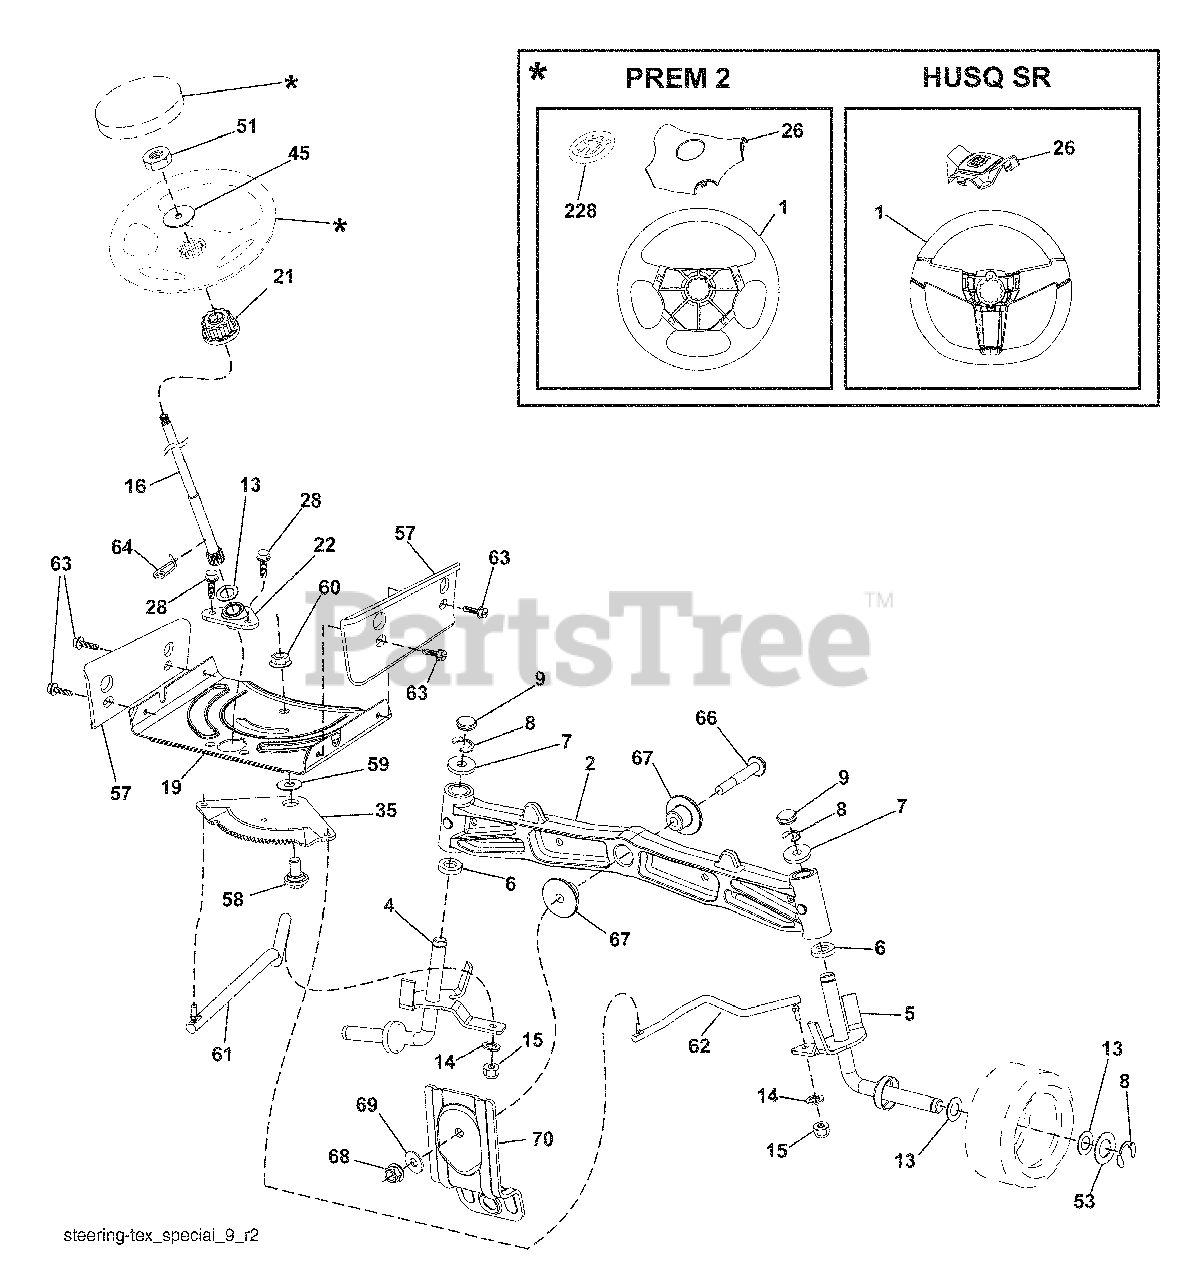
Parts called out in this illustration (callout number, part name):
1	Wheel, Steering
2	Axle Asm., Front
4	Spindle Asm., LH
5	Spindle Asm., RH
6	Bearing, Race Thrust Harden
7	Washer 25/32 x 1-5/8 x 16 Ga.
8	Ring, Clip #T5304-75
9	Cap, Spindle
13	Washer 25/32 x 1-1/4 x 16 Ga.
14	Washer, Lock Hvy Hlcl Spr 3/8
15	Nut, Crown Lock 3/8-24 unf
16	Shaft Steering
19	Plate Steering
21	Adapter, Wheel Steering
22	Bushing, Strg. Blk
26	Insert, Wheel Steering
28	Screw 3/8-16 x 3/4
35	Gear, Sector Plate
45	Washer 9/16 ID x 2-3/8 OD 12 Ga.
51	Nut Hex Jam Toplock 1/2-20 unf
53	Washer Hardened .793 x 1.637 x .060
57	Bracket Upstop
58	Bolt Shoulder Sector Pivot CFM
59	Washer Thrust Sector Steering
60	Nut Flange Lock 5/8-11
61	Draglink, LH
62	Draglink, RH
63	Screw 5/16-18 x 3/4
64	Retainer Clip Spring Steering
66	Bolt Hex Fghd 7/16-14 x 3 Serr
67	Bushing PM Front Axle
68	Nut Lock Flange 7/16-14 Gr. 5
69	Washer 1.5 x .505 x .118
70	Bracket Deck Susp. Front
228	Decal Wheel Steering
